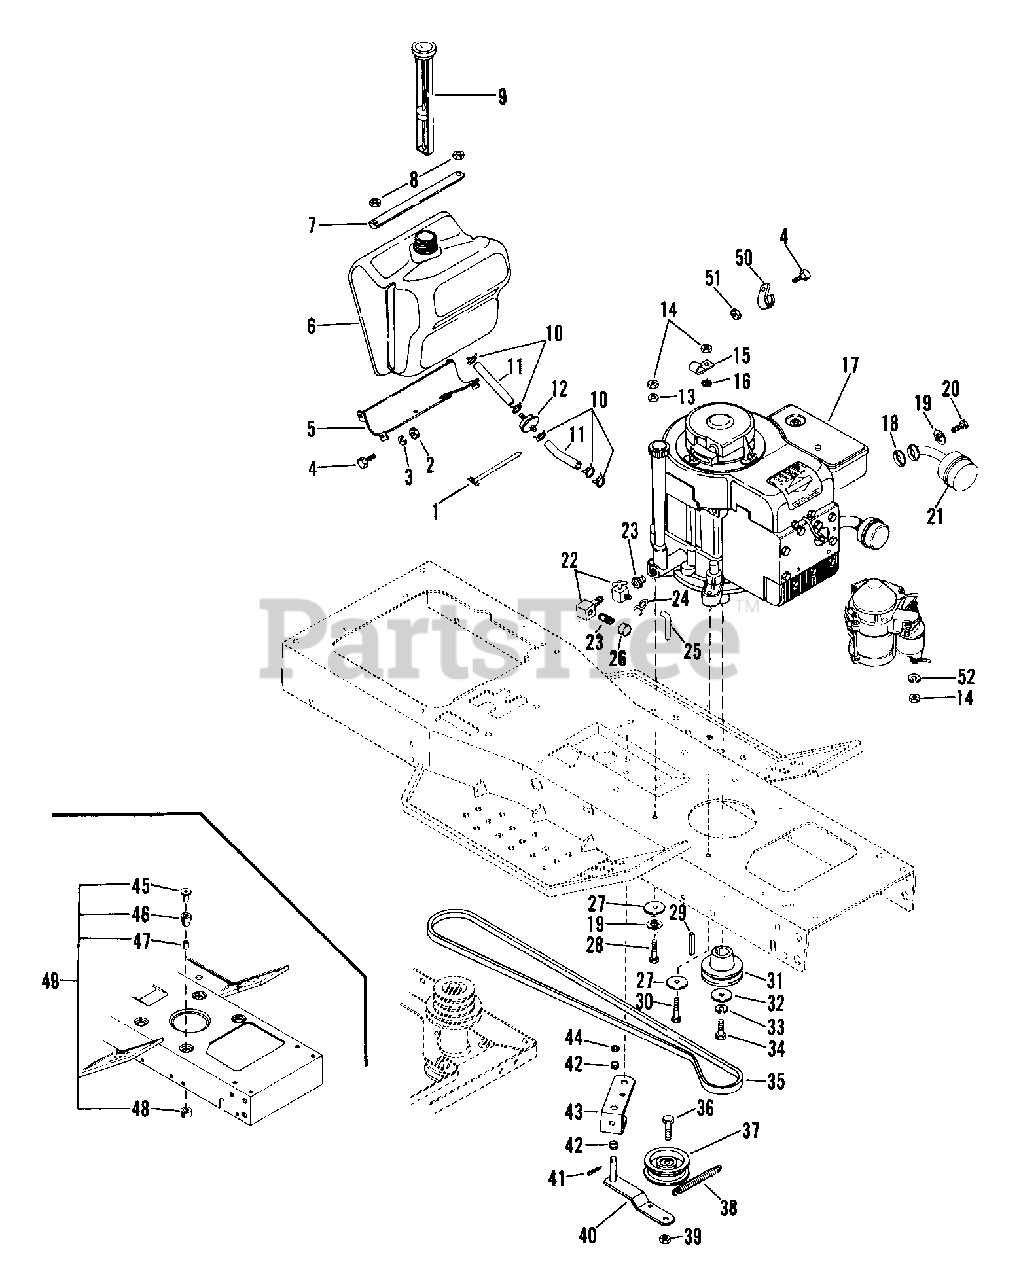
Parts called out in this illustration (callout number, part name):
1	TIE DOWN
2	NUT-HEX .250-20 PL
3	WSHR-LK .250X.077 HVY PL
4	BLT-HEX .25-20X.50 PL GR2
5	LOWER TANK SUPPORT
6	FUEL TANK
7	CLAMP STRAP
8	NUT-LK TOP .250-20 PL
9	FUEL GAUGE
10	CLAMP-HOSE WIR.490/.510X.092#8
10	HOSE CLAMP
11	FUEL LINE 1/4 X 67"
11	FUEL LINE
12	FUEL FILTER
13	WSHR-FL-STL.312X.734X.065PL
13	WSHR-LK .312X.097 PL HVY
14	NUT-LK-TOP .312-18 GR C PL
14	NUT M (ND)
15	J-CLAMP
16	WSHR-LK-EXT .313X.030 PL
17	11 HP BRIGGS ENGINE
17	11 HP B&S VERTICAL SHAFT IC
17	10 HP TECUMSEH ENGINE
17	10HP TEC ELEC START SSI BAL
17	12 HP B&S VERTICAL SHAFT IC
17	12.5 HP KAWASAKI ENGINE
18	GASKET - EXHAUST FLANGE
19	WSHR-LK .312X.097 PL HVY
20	SCR-SKH .31-18X.75 PL
21	EXHAUST MUFFLER
22	DRAIN LOCK
22	PIPE FITTING 90 DEG. X 3/8 ELB
22	FITTING 90 DEGREE SPECIAL
23	BUSHING
23	OIL DRAIN PIPE
24	HOSE CLAMP
25	TUBE
26	PIPE CAP
26	HEX CAP
27	WSHR-FL-STL .312X1.62X.13
28	BLT-HEX .31-18X2.50 PL GR2
28	BLT-HEX .31-18X1.50 PL GR5
28	BLT-HEX M8 X 1.25X40
29	KEY-STR .25X2.0X.25
30	BLT-HEX .31-18X2.75 PL GR2
30	BLT-HEX .31-18X1.75 GR5
30	BLT-HEX M 8MM-1.25X25MM
31	ENGINE SHEAVE
32	WSHR-FL-STL .469X1.380X.125
32	WSHR-FL-STL .390X1.500X.125
33	WSHR-LK .438X.133 HVY
33	WSHR-LK .375X.115 HVY PL
34	BLT-HEX .44-20X1.00 GR5
34	BLT-HEX .38-24X1.25 BLKO GR5
34	BLT-HEX M10 X 1.5X28
35	V-BELT, 4L-RAW EDGE
36	BLT-HEX .38-16X1.50 PL GR5
37	IDLER-FLAT 2.75 X .38 DAYCO
38	SG-TENS .080X.470X4.88 WLD 30
39	NUT-LK TOP .375-16 GR C YWZC
40	IDLER ARM
41	PIN-COTR .12X1.0 PL
42	BSHG-FLG .372X.500X.312X.625NY
43	IDLER PIVOT
44	WSHR-FL-STL.406X.812X.065PL
45	SPACER-SHOULDER
46	BOTTOM ISOLATION MOUNT
47	RUBBER BUSHING
48	TOP ISOLATION MOUNT
49	ISOLATION MOUNT ASSEMBLY
51	NUT-LK-FLG .250-20 PL
52	WSHR-LK .313X.078 PL MED
